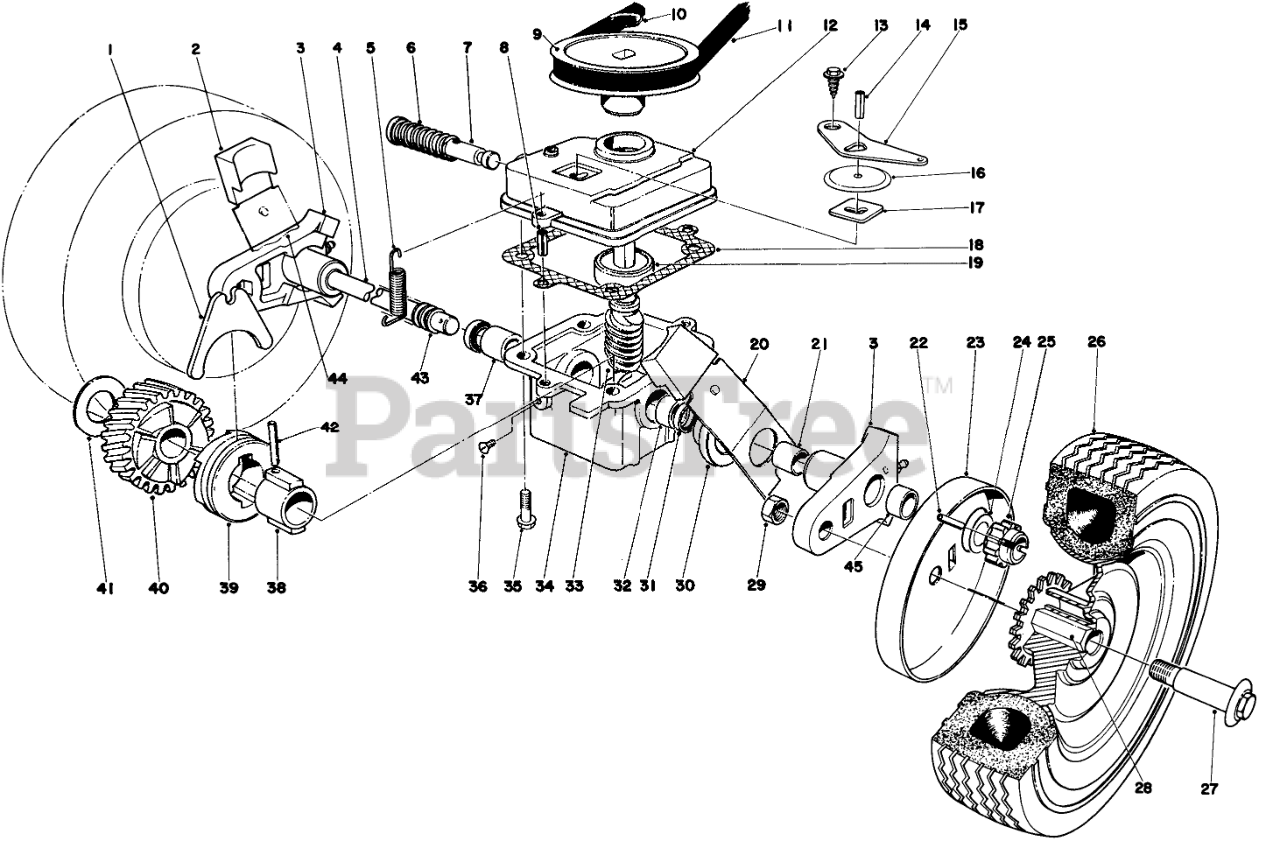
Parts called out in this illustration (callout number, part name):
1	SHIFTER FORK
2	KNOB-ARM
3	Pivot Arm (Incl. Ref. #21 & 45)
4	DRIVE SHAFT (SERVCE)
5	TENSION SPRING
6	SPRING
7	Shift Rod
8	3/16 X 1/2 ROLL PIN
9	PULLEY
10	PUSH-ON 93-3236
11	V BELT
12	Cover Gear Case
13	Screw
14	PIN-ROLL
15	SHIFTER ARM
16	TRANS DUST COVER
17	LATCH PLATE
18	GASKET
19	Bearing
20	SPRING ARM ASM SP LH
21	BUSHING
22	Pin
23	WHEEL COVER
24	WASHER-THRUST
25	Pinion
26	Wheel & Tire Assembly (Incl. Ref. #28)
28	WHEEL BUSHING
29	Nut
30	End Cap
31	Seal
32	Bushing
33	Worm Shaft & Gear (Incl. Ref. #40)
34	Gear Case (Incl. Ref. #31, 32 & 37)
35	Screw
36	NYLON SCREW
37	Bushing
38	SLEEVE
39	CLUTCH JAW
40	Helical Gear
41	THRUST WASHER
42	Pin
43	COVER-SHAFT, DRIVE
44	SPRING ARM ASM SP RH
45	BUSHING
